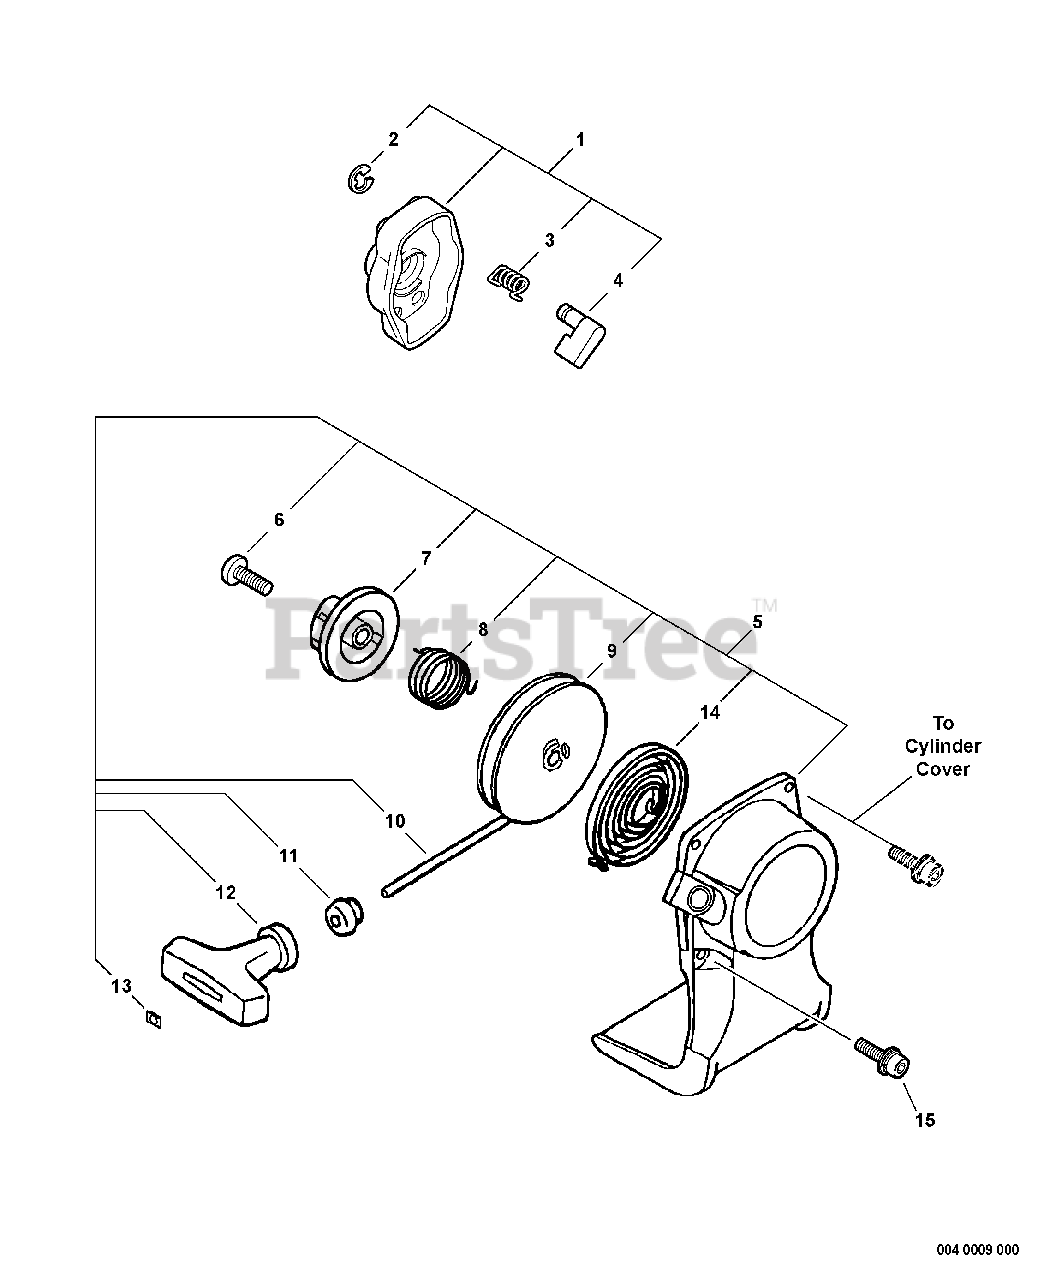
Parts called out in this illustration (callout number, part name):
1	PAWL ASSY, STARTER
2	E-RING 4
3	SPRING, RETURN
4	PAWL, STARTER
5	STARTER, RECOIL
6	SCREW
7	PLATE, CAM (NLA SEE PB 15-06)
8	SPRING, TORSION
9	REEL, ROPE
10	ROPE, STARTER 3×700
11	GUIDE, ROPE
12	GRIP, STARTER
13	RETAINER, ROPE
14	SPRING, RECOIL
15	BOLT 4×16
